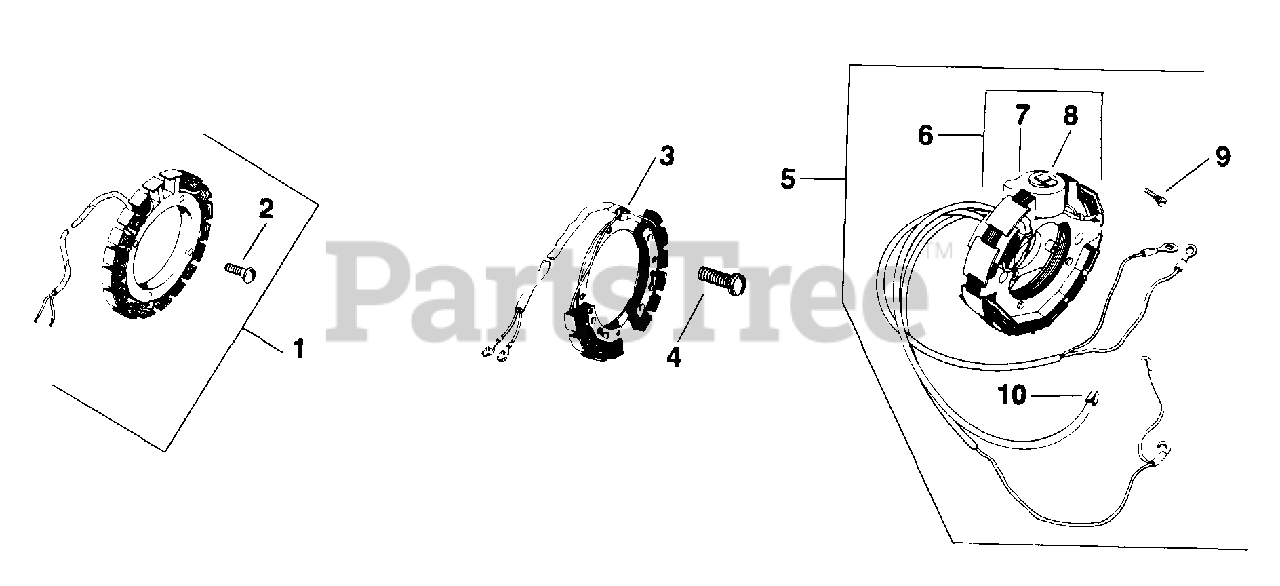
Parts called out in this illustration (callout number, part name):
4	SCREW - DISCONTINUED
6	KIT, COIL
8	KIT, CLIP - DISCONTINUED
10	LEAD - DISCONTINUED
